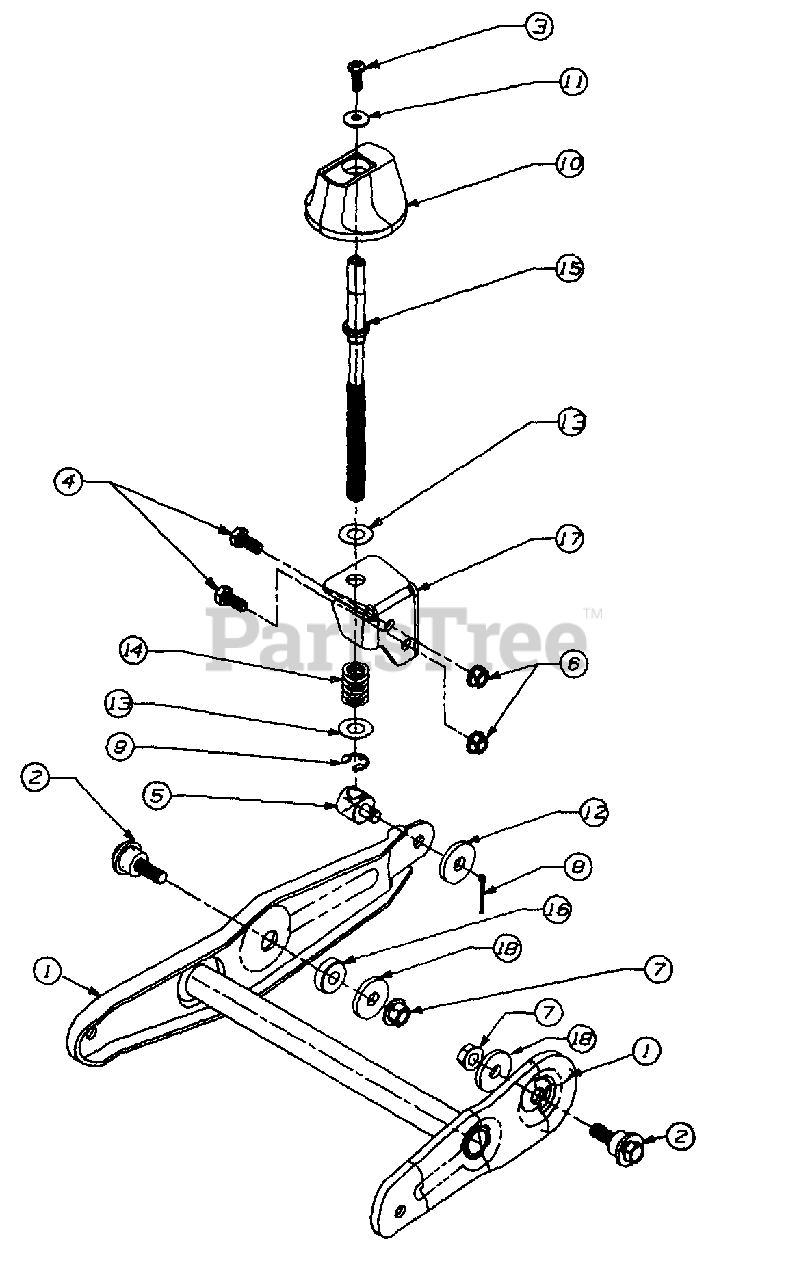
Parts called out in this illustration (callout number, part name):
3	SCREW-MACHINE PAN HD.
4	SCREW-HEX
5	FERRULE-ADJUSTABLE
6	NUT-HEX FLANGE
7	NUT-HEX FLANGE LOCK
8	PIN-COTTER
9	E-RING
10	PLASTIC KNOB
11	BELL WASHER
12	FLAT WASHER
13	FLAT WASHER
14	COMPRESSION SPRING
15	ADJUSTABLE ROD
16	SPACER
